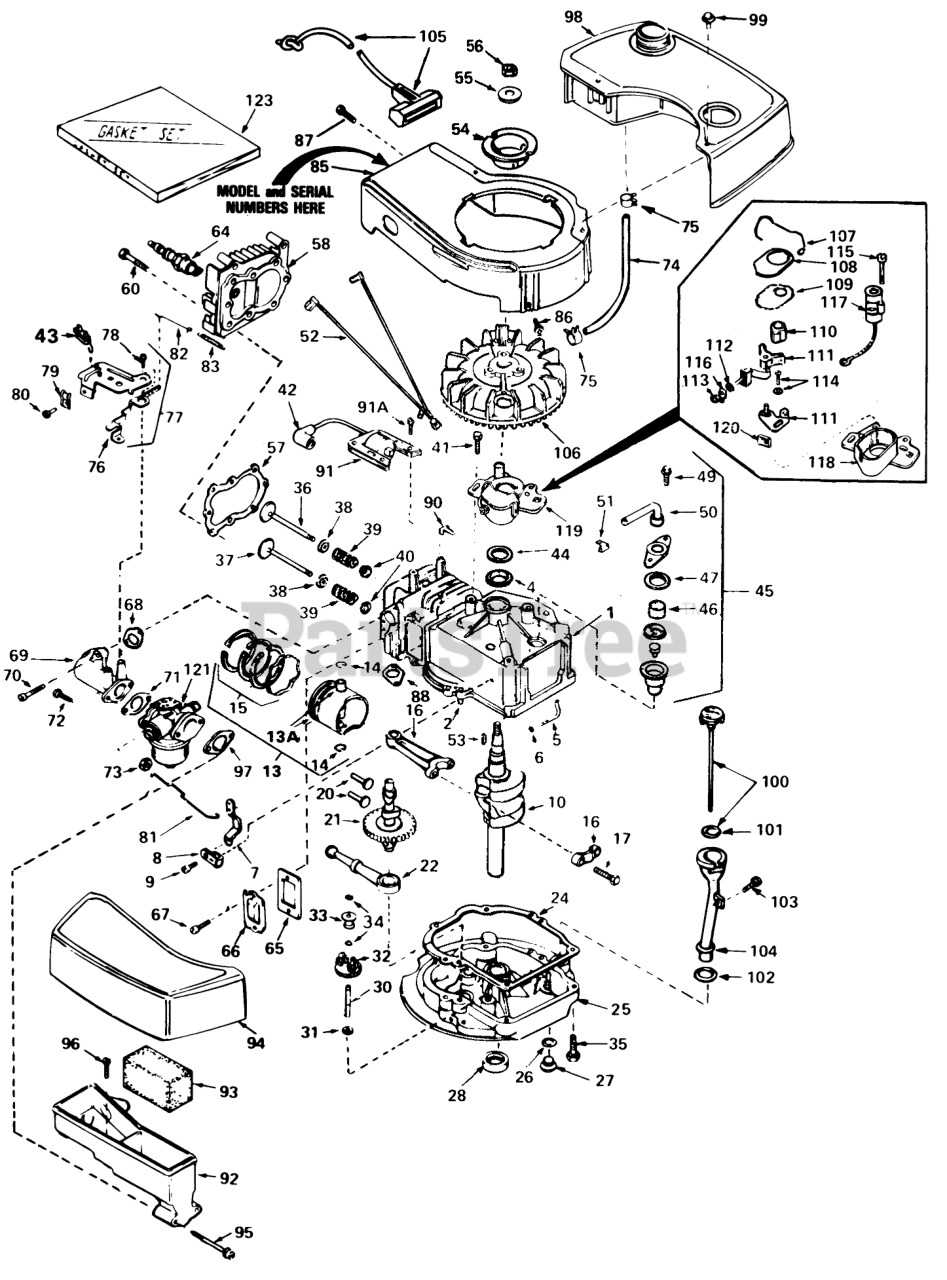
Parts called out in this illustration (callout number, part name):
1	Cylinder Assy. (Incl. Ref. #2 & 4)
2	Pin-Dowel
4	Seal-Oil
5	Rod, Governor (Incl. Ref. #6)
6	Washer-Flat
7	Governor Lever
8	Clamp-Lever, Governor
9	Screw
10	Crankshaft
13	Piston, Pin & Ring Assy. (Incl. Ref. #13A, 14 & 15)(Std.)
13	Piston, Pin & Ring Assy. (Incl. Ref. #13A, 14 & 15) (.010 Oversize)
13	Piston, Pin & Ring Assy. (Incl. Ref. #13A, 14 & 15) (.020 Oversize)
13A	Piston & Pin Assy. (Incl. Ref. #14) (Std.)
13A	Piston & Pin Assy. (Incl. Ref. #14) (.010 Oversize)
13A	Piston & Pin Assy. (Incl. Ref. #14) (.020 Oversize)
14	Ring-Retaining, Piston Pin
15	Ring Set Piston (Std.)
15	Ring Set Piston (.010 Oversize)
15	Ring Set Piston (.020 Oversize)
16	Rod Assy., Connecting (Incl. Ref. #17)
17	Bolt-Rod, Connecting
20	Lifter-Valve
21	Camshaft(Mech.Comp. Release)
22	Oil Pump ASM
24	Gasket, Mounting
25	Flange Assy., Mounting (Incl. Ref. #26 thru 30)
26	Gasket-Oil Drain
27	Plug Oil Drain
28	Seal Oil
30	Shaft-Governor
31	Washer-Flat
32	Gear Assy., Governor (Incl. Ref. #31)
33	Spool-Governor
34	Ring-Retaining
35	Screw (1/4-20 x 1-1/4)
36	Valve Intake (Std.)(Incl. #38, 39 & 40)
36	Valve, Intake (1/32" Oversize) (Incl. Ref. #38, 39 & 40)
37	Valve, Exhaust (Std.) (Incl. #7, 8 & 9)
37	Valve, Exhaust (1/32" Oversize) (Incl. Ref. #38, 39 & 40)
38	Cap-Upper Valve Spring
39	Spring-Valve
40	Cap-Valve, Spring
42	Cover-Spark Plug
43	Terminal
44	Gasket Stator
45	Breather Assy. (Incl. Ref. #46, 47, 49, 50 & 51)
46	Element-Breather
47	Gasket-Breather
49	Screw (10-24 x 9/16)
50	Tube, Breaker
51	Clip, Breather
52	Wire Ground
53	682488 LB GRASS HI-
54	Hub-Starter
55	Washer-Belleville
56	Nut-Flywheel
57	63573 GIL 42 SNWTHW
58	Head-Cylinder
60	Screw
64	Plug, Spark (J17LM or equiv.)
64	Plug, Spark (Champion RCJ-8)
65	Gasket-Breather
66	Cover-Valve
68	Gasket-Intake
69	Pipe, Intake (Incl. Ref. #68)
70	Screw (1/4-20 x 1)
71	Gasket-Carburetor
72	Screw (1/4-28 x 7/8)
73	Nut and Lock Washer (1/4-28)
74	Line-Fuel
75	Clamp-Line, Fuel
76	Lever Control
77	Control Assy., Speed (Incl. Ref. #43, 76 & 78)
78	Screw, Hex Washer Hd Shoulder Self-Tap
79	Conduit
80	Screw (10-32 x 3/8)
81	Link-Throttle
82	Link Governor Spring
83	Spring Governor
85	Housing Blower
86	Screw
87	Screw (10-24 x 9/16)
88	Gasket Exhaust
90	Clip-Wire
91	Lamination & Coil Assy. (Incl. Ref. #42)
91A	Screw
92	Body Air Cleaner
93	Filer, Air
94	Cove, Air Cleaner
95	Screw Fil Hd.
96	Screw, Hex Hd.
97	Gasket-Air Cleaner
98	Tank, Fuel
99	Screw (10-32 x 35/64)
100	Dipstick, Oil (Incl. Ref. #101) (Twist Lock)
103	Screw (10-32 x 1/2)
104	Tube-Oil Fill
105	Rope Assy., Starter
106	FIywheel
107	Spring Breaker Box
108	Cover-Dust
109	Gasket-Dust Cover
110	Cam-Breaker
111	Breaker Assy.
114	Breaker Screw
115	Condenser Screw
116	Terminal, Ground
117	Condenser
118	Stator Plate
119	Stator Plate Assy. (Incl. Ref. #107, 111 thru 118 & 120)
120	Felt,Cam Wiper
121	Carburetor (Incl. Ref. #71)
123	Gasket Set
